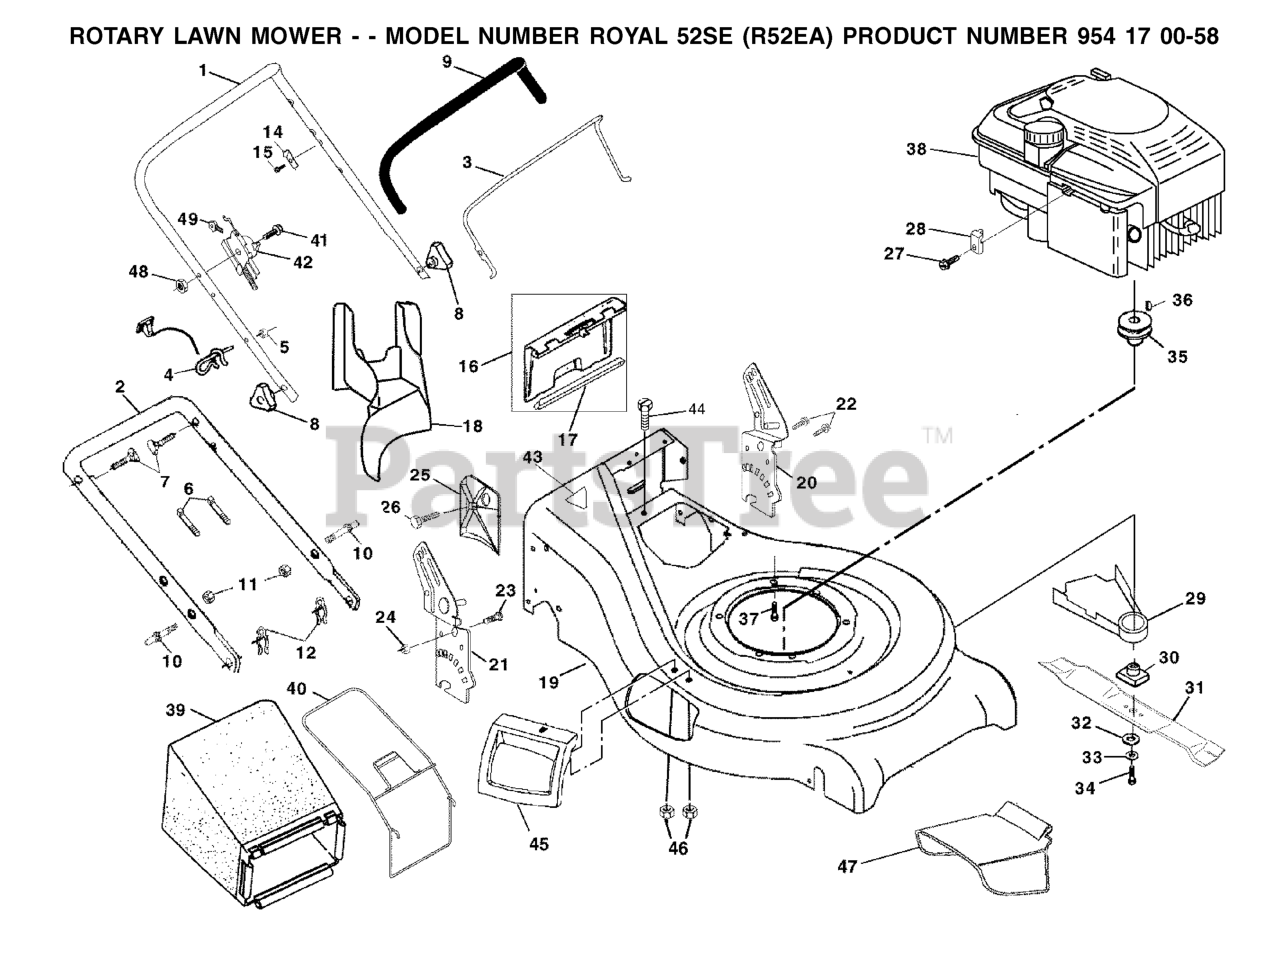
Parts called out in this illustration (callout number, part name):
1	HANDLE, UPPER DLX COMF. (GRIP)
2	HANDLE
3	CONTROL BAR
4	ROPE, GUIDE
5	NUT
6	TIE GUIDE
7	HANDLE BOLT
9	GRIP.HANDLE.FOAM
10	BOLT
11	NUT
12	HAIRPIN COTTER
14	BRACKET UPSTOP
15	SCREW.HEX.HEAD.WASHER.10-16
16	KIT.DOOR.REAR.21.WRAPPED.BLACK
17	SEALING
18	MULCH PLUG
20	.RACKET
21	RIGHT HANDLE BRKT. ASSM.
22	SELF-TAPPING SCREW 5/16-18X3/4
23	BOLT, HEX HEAD 5/16-18
24	LOCKNUT
25	CLIPPING DEFLECTOR
27	SCREW.HEX.HEAD.WASHER.10-16
28	CABLE CLAMP(ENGINE)
29	DEBRIS SHIELD
30	BLADE ADAPTOR
32	WASHER,HARDEN
33	LOCKWASHER
34	SCREW, HEX HD 3/8-24 X 1-3/8
35	ENGINE.PULLEY.FWG
36	HI PRO KEY PM WSL
37	BOLT 3/8-16X1-1/8
40	FRAME.GRASS.CATCHER.WALK.21"
41	SCREW 1/4-20 X 2.12
43	DECAL MOWER CUT/FINGER
45	MULCH COVER
47	DEFLECTOR.21.MCUT.RWGD.GRAY
48	LOCK NUT
49	KEY.MOLDED.GENERIC
